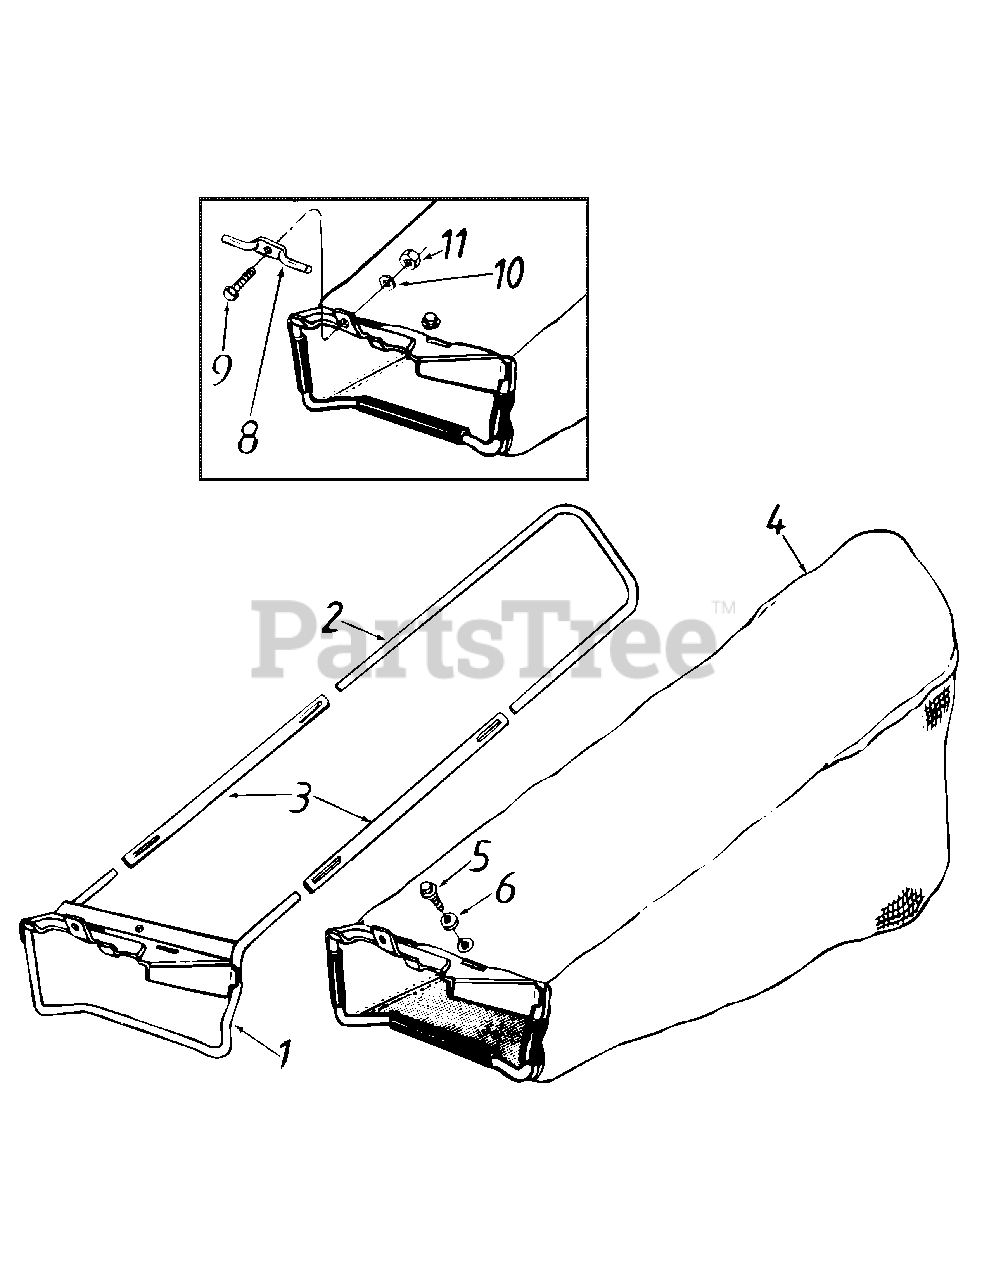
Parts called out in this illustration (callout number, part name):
4	Grass Bag
5	Hex Wash. Hd. TT-Tap Scr. 1/4-20 x 5" Lg.
6	Bell-Wash. 1/4" I.D.
8	Grass Bag Hook
9	Hex Bolt 1/4-20 x .62" Lg.
10	L-Wash. 1/4" I.D.
11	Hex Nut 1/4-20 Thd.
